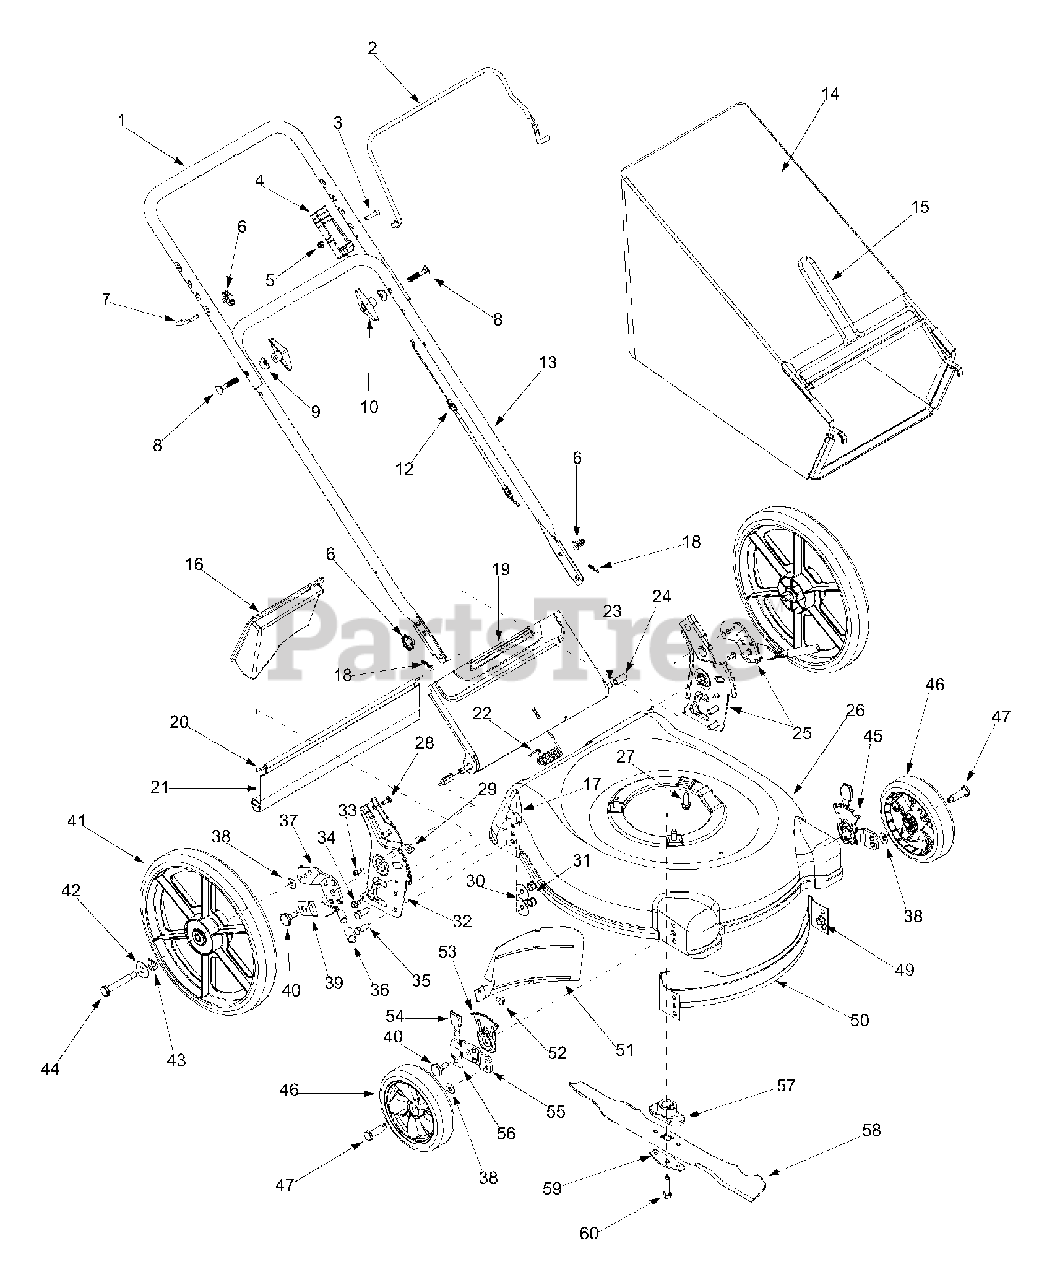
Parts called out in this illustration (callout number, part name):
3	C-Sunk Screw 1/4-20 x 1.3"
4	Throttle Housing
5	Hex Lock Nut 1/4-20
6	Handle Knob
7	Rope Guide
8	Carriage Bolt 5/16-18 x 2"
9	Shoulder Washer .320 ID x .930 OD
10	Wing Nut
12	Blade Control Cable 43"
12	Blade Control Cable 40.5"
14	Grass Bag
16	Rear Mulch Plug
18	Hairpin Clip
21	Trailshield
22	Door Spring
23	Chute Door Pivot Rod
24	Spacer .375 O.D. x .50 I.D. x 1.02"
25	Handle Bracket Assembly - RH & LH
28	Hex Carriage Screw 1/4-20
29	Flange Lock Nut 3/8-16
30	Bell Washer .390 ID x .380 OD
31	Hex Lock Nut 3/8-16
33	Machine Screw 1/4-20 x .500
34	Hex Washer Screw 1/4-14 x .625
35	Hex Cap Screw 3/8-16 x 1.0
36	Foam Grip
37	Pivot Bar - RH
37	Pivot Bar - LH
38	Spring Washer .375 ID x .870 OD
39	Spring Lever
40	Shoulder Screw
41	Rear Wheel Assembly 14 x 1.8
42	Flat Washer .510 ID x 1.37 OD
43	Wave Washer .500 ID x 1.0 OD
44	Shoulder Screw
45	Front Height Adjuster - RH
45	Front Height Adjuster - LH
46	Front Wheel Assembly 7 x 1.8
47	Shoulder Bolt
49	Flange Lock Nut 3/8-16
52	Tap Screw 1/4-14 x .625.
53	Height Adjustment Plate
54	Height Adjustment Knob
56	Spring Lever
57	Blade Adapter
58	21" Mulching
58	21" Standard
59	Blade Bell Support
60	Hex Cap Screw 3/8-24 x 1.5
